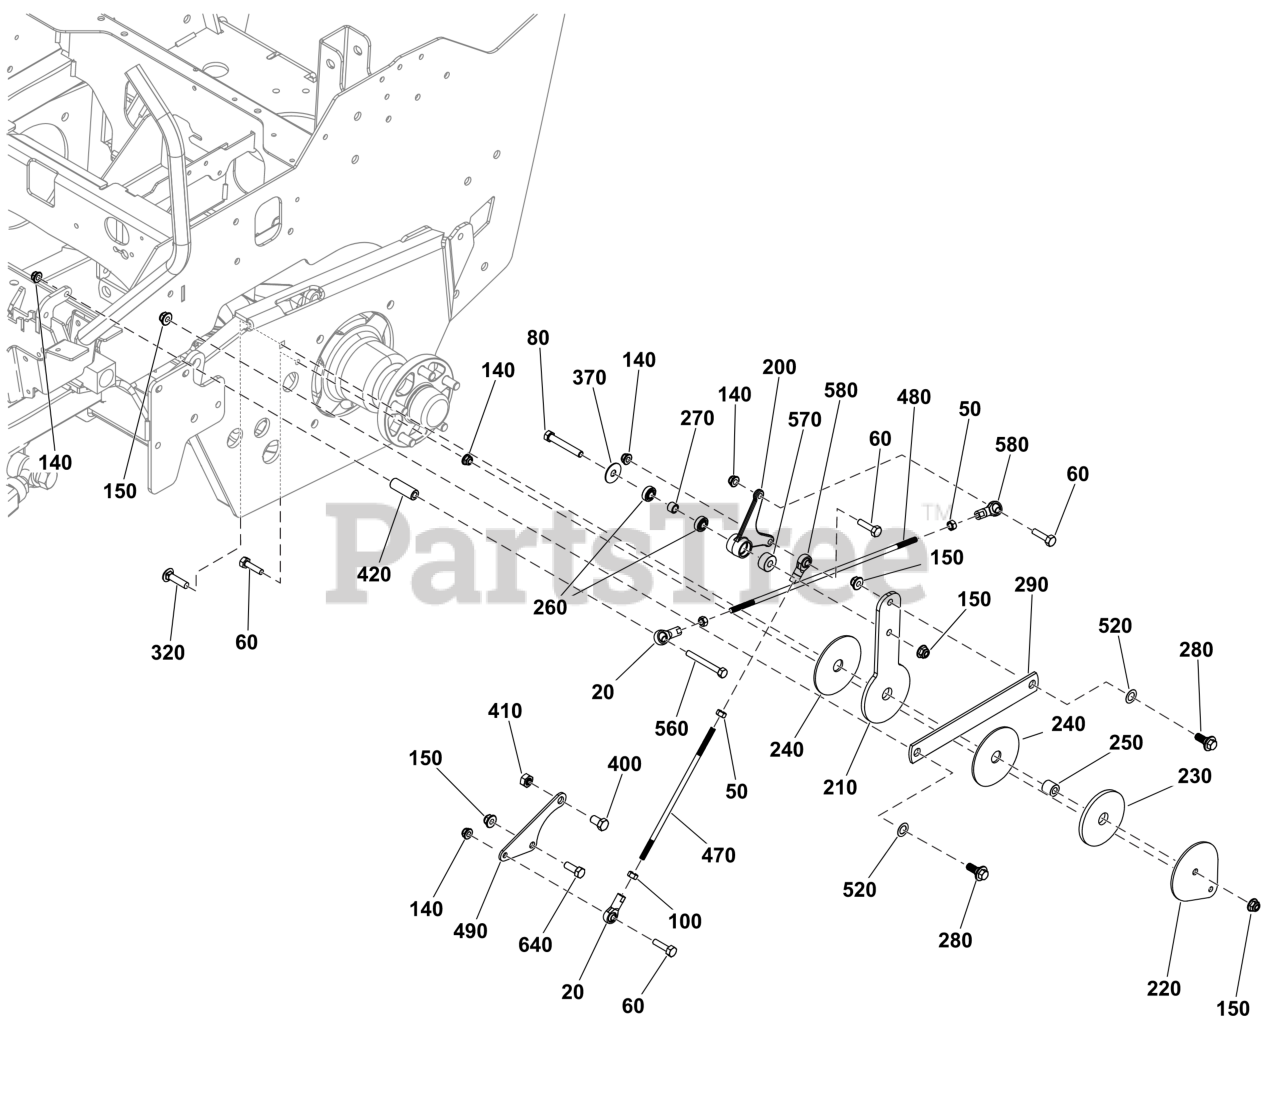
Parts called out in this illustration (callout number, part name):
20	BALL JOINT 5/16-24 RH
50	NUT, 5/16-24 HEX, LH
60	BOLT, 5/16-18 X 1-1/4
140	NUT
150	NUT, 3/8-16 HEX NYLOCK
200	PIVOT, CONTROL SYSTEM
210	PLATE, CTRL SYST ARM
220	PLATE, CTRL SYSTEM LK
230	PAD, .77 X 3.50 X .25
240	PAD, CONTROL SYSTEM
250	SPACER, .39X.75X.69
260	BEARING, .375ID
270	SPACER, .39X.55X.38
280	BOLT, Washer
290	LINK, Control
320	BOLT, 3/8-16 X 1-1/2
370	WASHER, 3/8" FENDER
400	BOLT, 7/16-14
410	NUT, 7/16-14 HEX
470	ROD, 5/16-24
480	ROD, HYDRO LINKAGE
490	PLATE, CONTROL MOUNT
520	WAVE WASHER
560	BOLT, 5/16-18 X 2-3/4
580	BALL JOINT 5/16-24 LH
640	BOLT, 3/8-16 X 1" GD5
